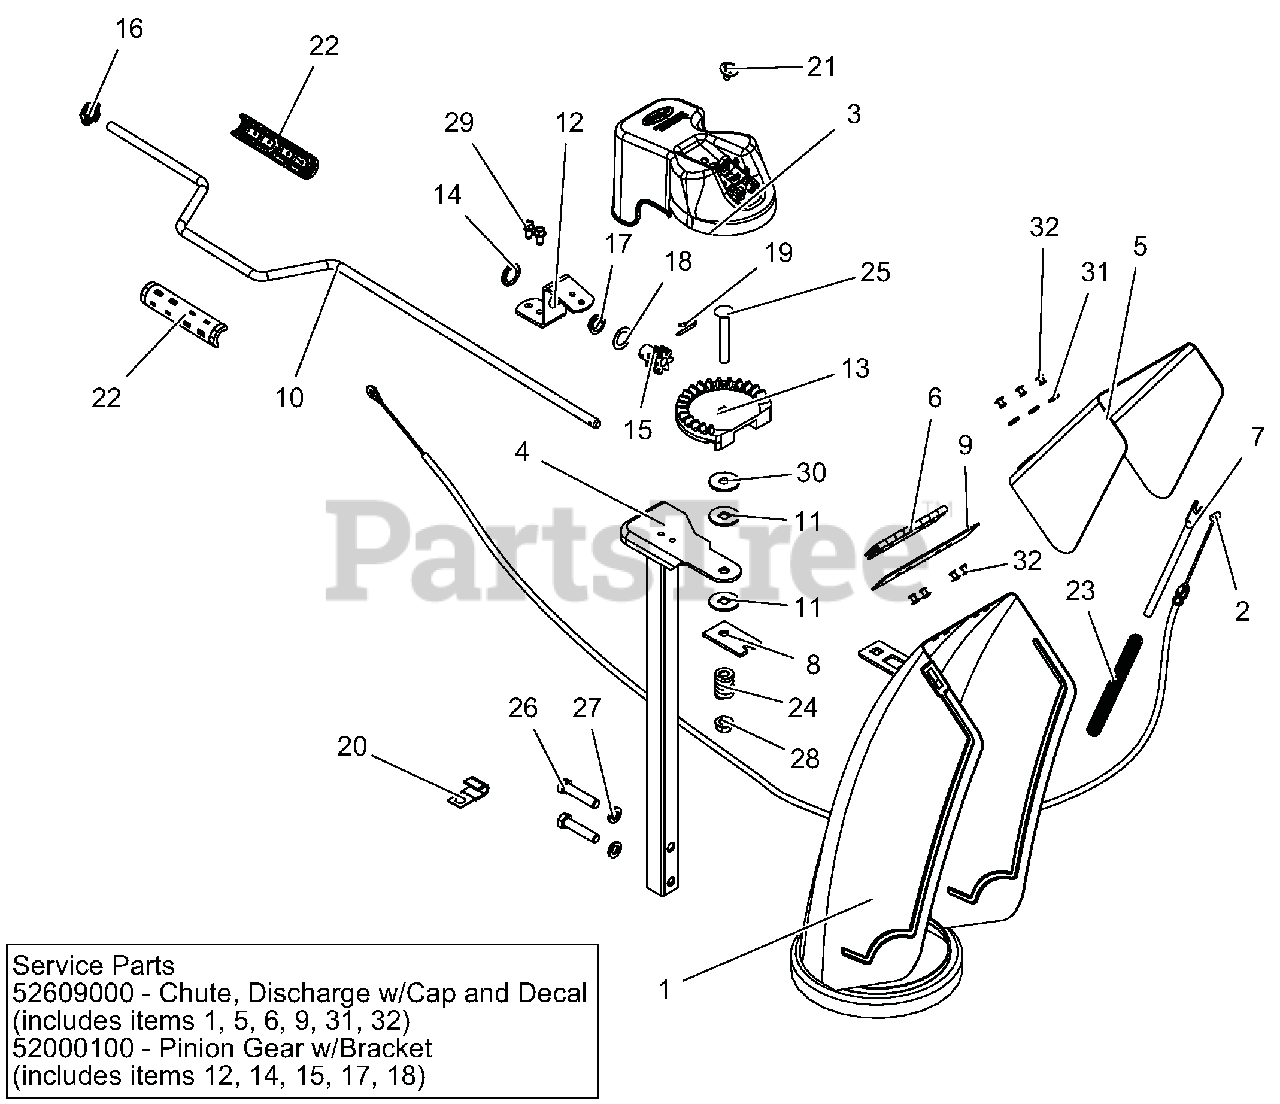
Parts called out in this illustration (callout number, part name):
1	CHUTE, DISCHARGE CRANK+REMOTE
2	CABLE, DEFLECTOR-COATED
3	DELUXE COVER W/SHEAR BOLTS KIT
4	PEDESTAL, CHUTE - CRANK
5	CAP, LARGE
7	ROD, DEFLECTOR CAP
8	PLATE, FRICTION
9	CAP SEAL 5.50
10	ROD, CHUTE CRANK
11	FRICTION WASHER
12	BRACKET, PINION GEAR
13	CHUTE GEAR
14	PUSHNUT .625
15	PINION GEAR - CHUTE
16	CRANK BUSHING, NYLON CHUTE BK
17	BUSHING, POLYLINER-.63 SNAPIN
18	WSHR-THRST .625 X 1.0 X .03
19	PIN, SPRING CLIP
20	J-CLAMP
21	SCR-TAP .25-20X.50 LGHWH TR YZ
22	KNOB, CRANK-SNAP
23	SG-COMP .08X.40X6.50 14#/IN
24	SG-COMP .187X.56X1.62
25	@BLT-RDHDSQNK .38-16X2.50 G5YZ
26	@BLT-HEX .38-16X1.75 GR5 YWZC
27	@WSHR-LK .38X.094 REG YWZC
28	@NUT-LK-TOP-FLG .38-16 YWZC
29	SCR-TAP .25-20X.50 HWH TR YWZ
30	@WSHR-FL-STL .406X1.25X.10 ZC
31	WSHR-FL-STL .196X.500X.06 YZ
32	RVT-POP .187 YZ
